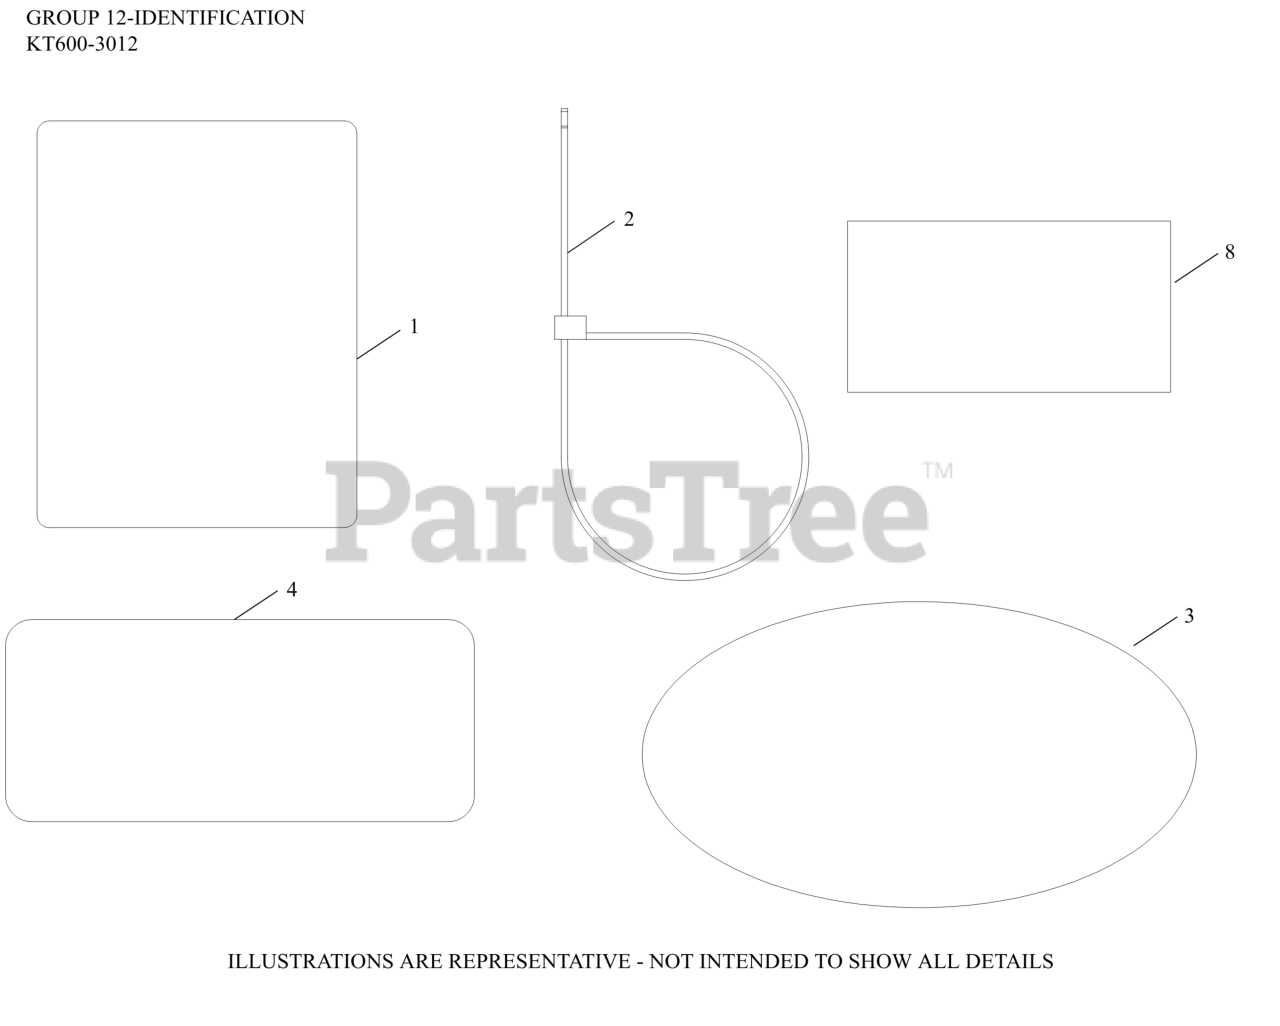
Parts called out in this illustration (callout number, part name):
1	LABEL, CLEAR LAMINATION
3	LABEL, 6600 SERIES (17HP)
4	LABEL, CANADIAN COMPLIANCE
8	DECAL, USA
